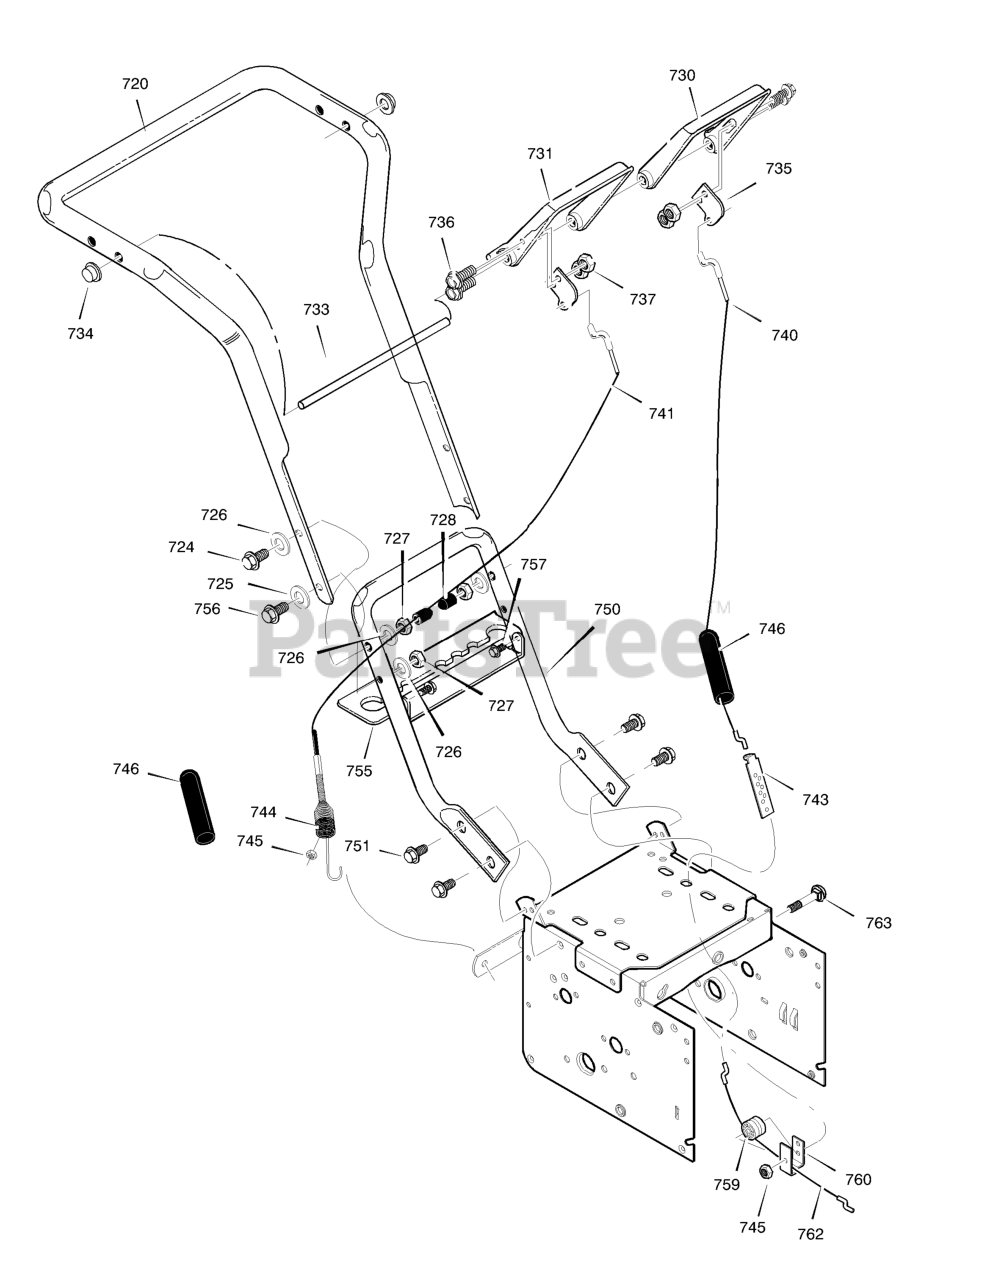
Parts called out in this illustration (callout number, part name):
724	SCREW
725	WASHER, FLAT
726	WASHER
727	NUT
728	PLASTIC-STOP
730	CLUTCH, LEFT HANDLE CONTROL
731	CLUTCH, RIGHT HANDLE CONTROL
733	ROD, PIVOT HANDLE
734	PUSH ON CAP
735	PLATE, CABLE PIVOT
740	CABLE, CLUTCH
741	CABLE, AUGER CLUTCH
743	BRKT, CABLE ADJUST
744	SPRING, AUGER CLUTCH
745	LOCKNUT
746	BOOT, CLUTCH SPRING
750	HANDLE, LOWER
751	SCREW
755	BRACKET, GEAR SELECTOR
756	SCREW, .31-18 x 2.00
757	SCREW, 1/4-20 X 0.63
759	SPOOL-CABLE, AUGRT CLUTCH
760	BRACKET, CABLE SPOOL YZ
762	CABLE, LOWER DRIVE 12"
763	BOLT, HEX 1/4-20 X 1.50 YZ
